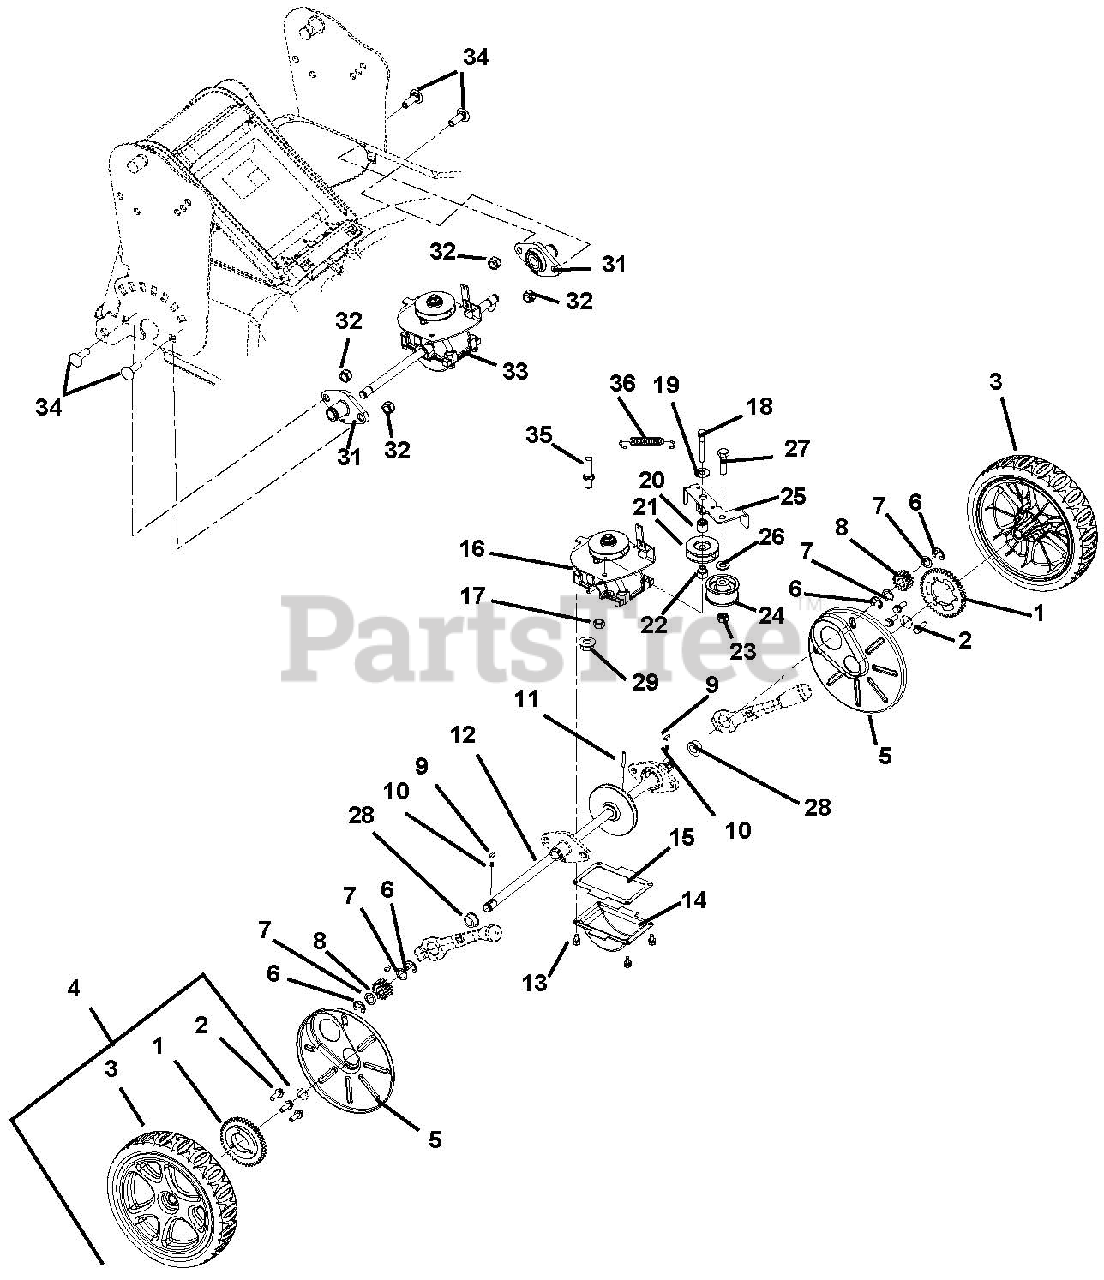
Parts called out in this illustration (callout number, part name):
1	GEAR, WHEEL
2	SCR-TAP .25-15X.75 HI-LO
3	WHEEL-8.5" WBLM ASSY
4	ASSY, LM REAR WHEEL
5	WHEEL COVER
6	RG-RTNG-EXT .500X.042 (E)
7	WASHER, .500X.750X.020 THRUST
8	PINION-WBLM DRIVE
9	KEY-WDRF .125X.50X.20 (HRDEND)
10	SPRING, .134X.180X.144 COMP.
11	PIN-ROLL .156X1.00
12	SHAFT, TRANSMISSION OUTPUT
13	@SCR-TAP 10-24X.375 HWH YZ TR
14	SUMP, GEARBOX
15	GASKET, TRANSMISSION
16	KIT, WBLM TRANS HOUSING
17	@NUT-LK-TOP-FLG .25-20 YWZC
18	BLT-HEX .25-20X2.25 GR8 YWZC
19	@WSHR-FL-STL.312X.734X.065 YWZ
20	SPACER, IDLER ARM
21	IDLER, 3L FRONT SIDE .38X1.875
22	SPACER, V-IDLER PULLEY
23	@NUT-LK-CTR .38-16 YWZC
24	IDLER - FLAT 1.875OD X .75WIDE
25	ARM, TRANSMISSION IDLER
26	@WSHR-FL-STL.406X.812X.065 YWZ
27	@BLT-HEX .38-16X1.38 GR5 YWZC
28	BUSHING, TRANS OUTPUT SHAFT
29	@NUT-SPNLK-FLG .25-20 YWZC
30	BRACKET, TRANSMISSION CONTROL
31	KIT, WHEEL MOUNT HUB SERVICE
32	@NUT-LK-TOP-FLG .31-18 YWZC
33	KIT, BLADE RUNNER TRANS SRVC
34	@BLT-RDHDSQNK .31-18X1.00 G5YZ
35	FINGER, BELT
36	SG-TENS .051X.60X2.25 WLD 7.0
